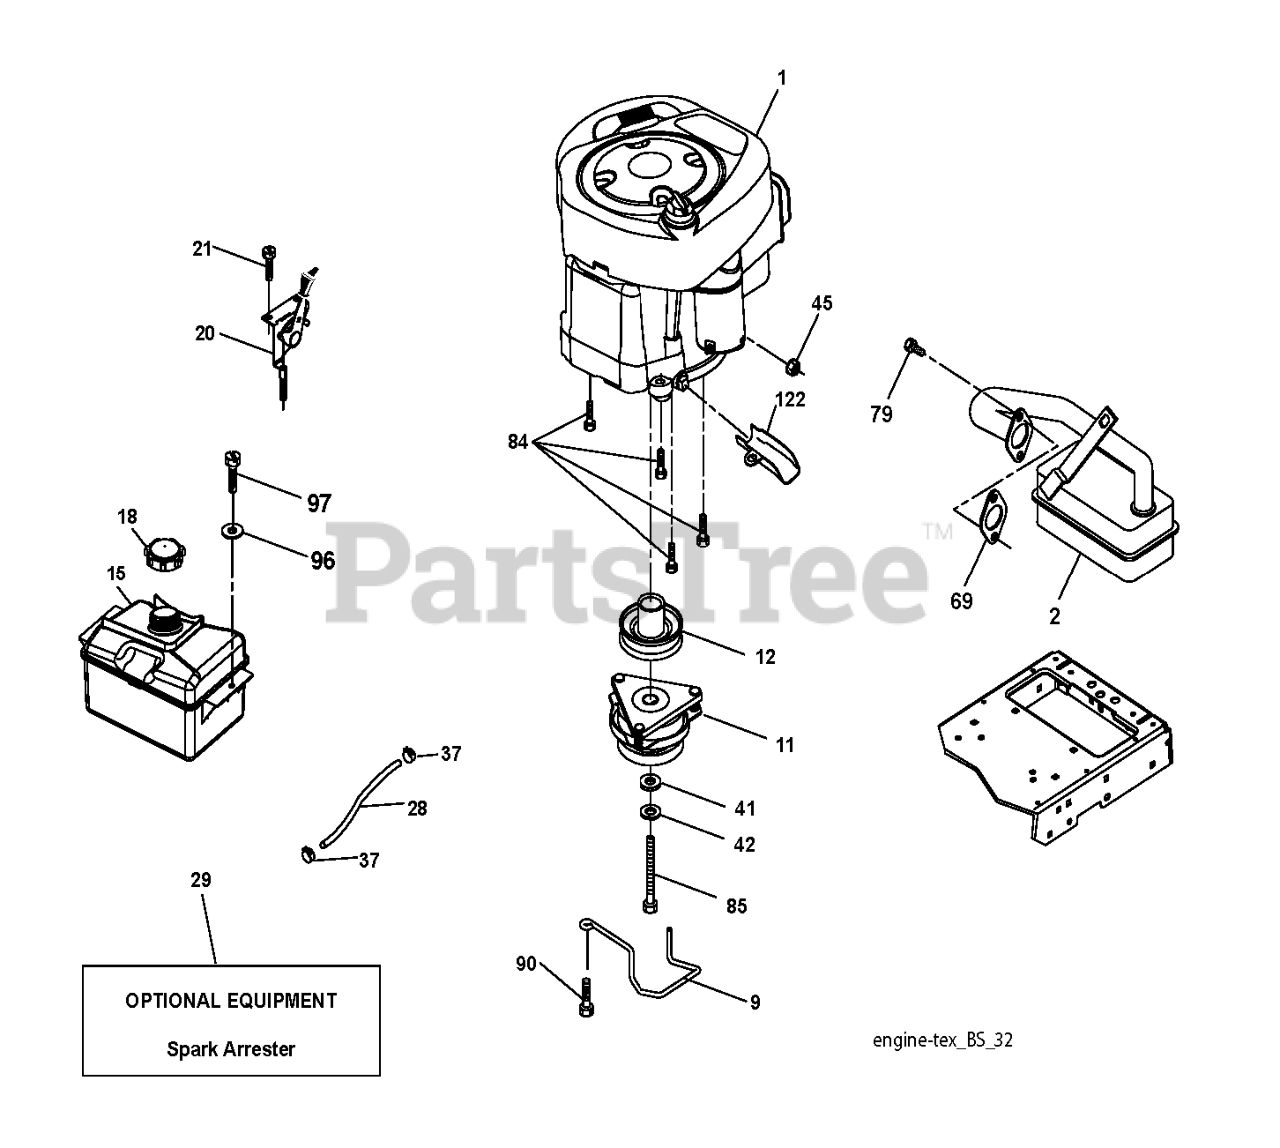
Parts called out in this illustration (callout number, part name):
2	MUFFLER.B&S.MODEL.21.11HP.OHV
9	KEEPER.BELT.ENGINE.3.25 (3 2)
11	RB.CLUTCH.OGURA.4.4.PD
12	PULLEY.ASM.ENG.OGURA.3
15	RP TANK FUEL FRT 1.5 GAL
18	CAP.FUEL.2.25"VENTED"
20	CONTROL.TH/CK.C.
21	SCREW.#10 X 0.750.BOS
28	LINE.FUEL.20
29	KIT.SPARK ARRESTOR 794945 B&S
37	HOSE CLAMP
42	LOCKWASHER
45	NUT
69	REPL BY 532 27 22-93
79	SCREW.SOCKET HD.5/16-1
84	SCREW.3/8-16
85	BOLT HEX 7/16-20X4-1/4"
90	SCREW 3/8-16X1
97	SCREW HEXWSHR 1/4-20X3/4
122	EXTENSION DRAIN OIL
